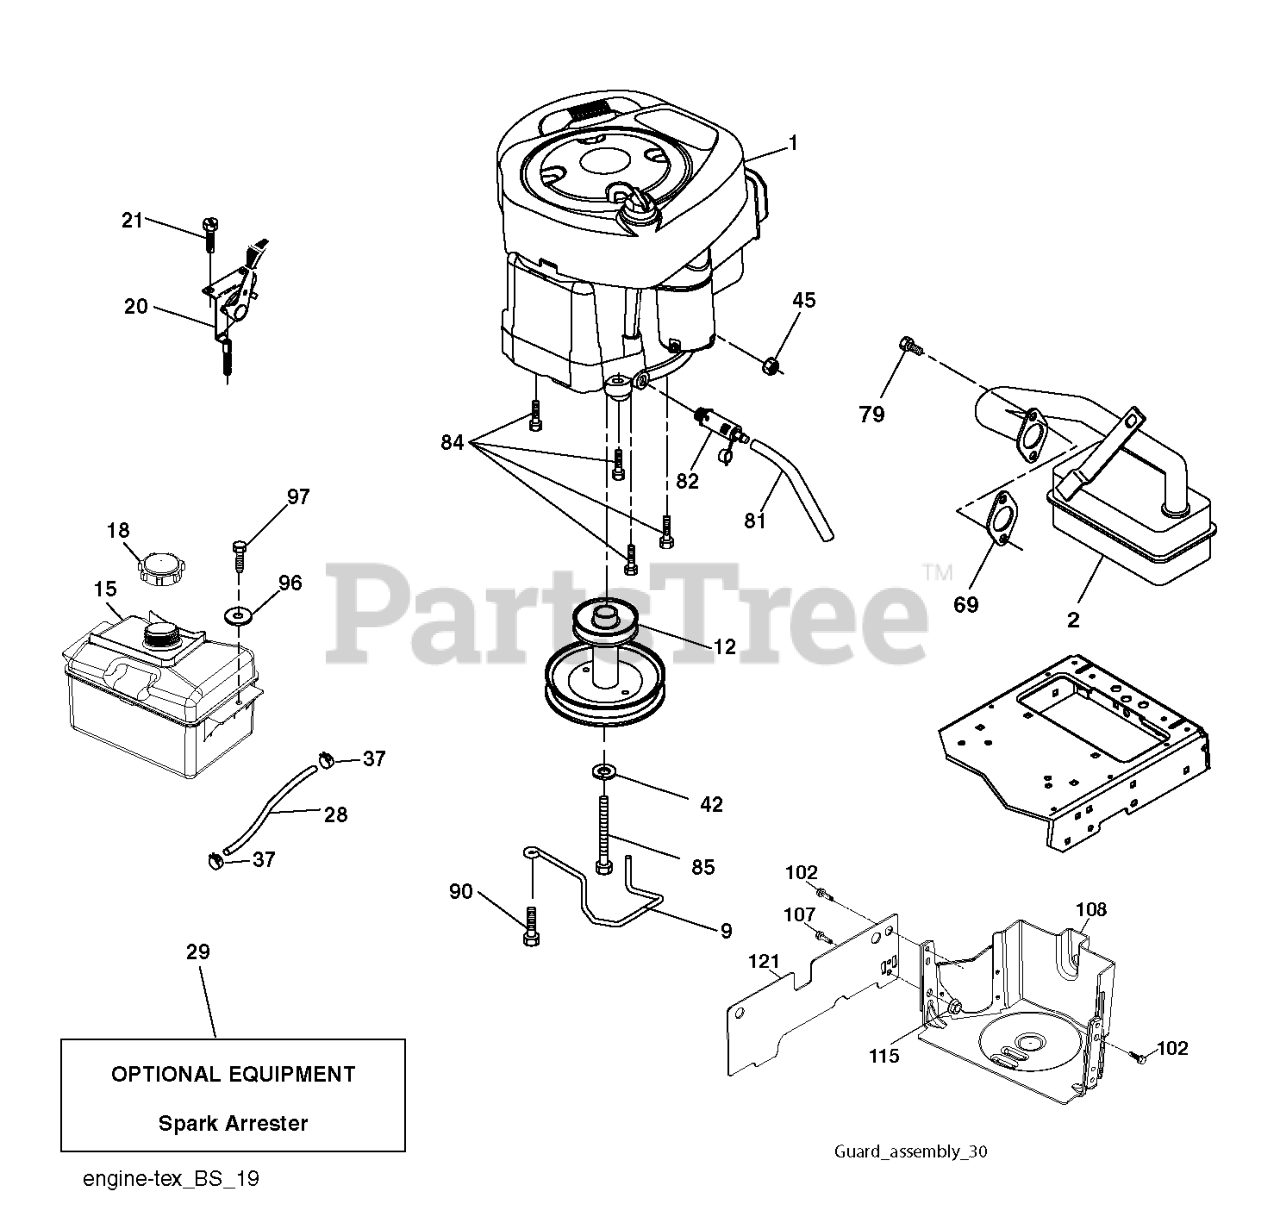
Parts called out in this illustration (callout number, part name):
2	MUFFLER.B&S.MODEL.21.11HP.OHV
9	KEEPER.BELT.ENGINE.3.25 (3 2)
12	PULLEY.ENG.CL.MECH.SLVR.LT/YT
15	RP TANK FUEL FRT 1.5 GAL
18	FUEL CAP
20	CONTROL.TH/CK.C.
21	SCREW.#10 X 0.750.BOS
28	LINE.FUEL.20
29	KIT.SPARK ARRESTOR 794945 B&S
37	HOSE CLAMP
42	LOCKWASHER
45	NUT
69	REPL BY 532 27 22-93
79	SCREW.SOCKET HD.5/16-1
81	TUBE, DRAIN OIL ASM.
82	PLUG DRAIN OIL EASY
84	SCREW.3/8-16
85	BOLT HEX 7/16-20X4-1/4"
90	SCREW 3/8-16X1
97	SCREW HEXWSHR 1/4-20X3/4
102	SCREW
107	SCREW.1/4-20X5/8
108	COVER PULLEY
115	PALNUT 1/4
121	SHIELD LEFT
